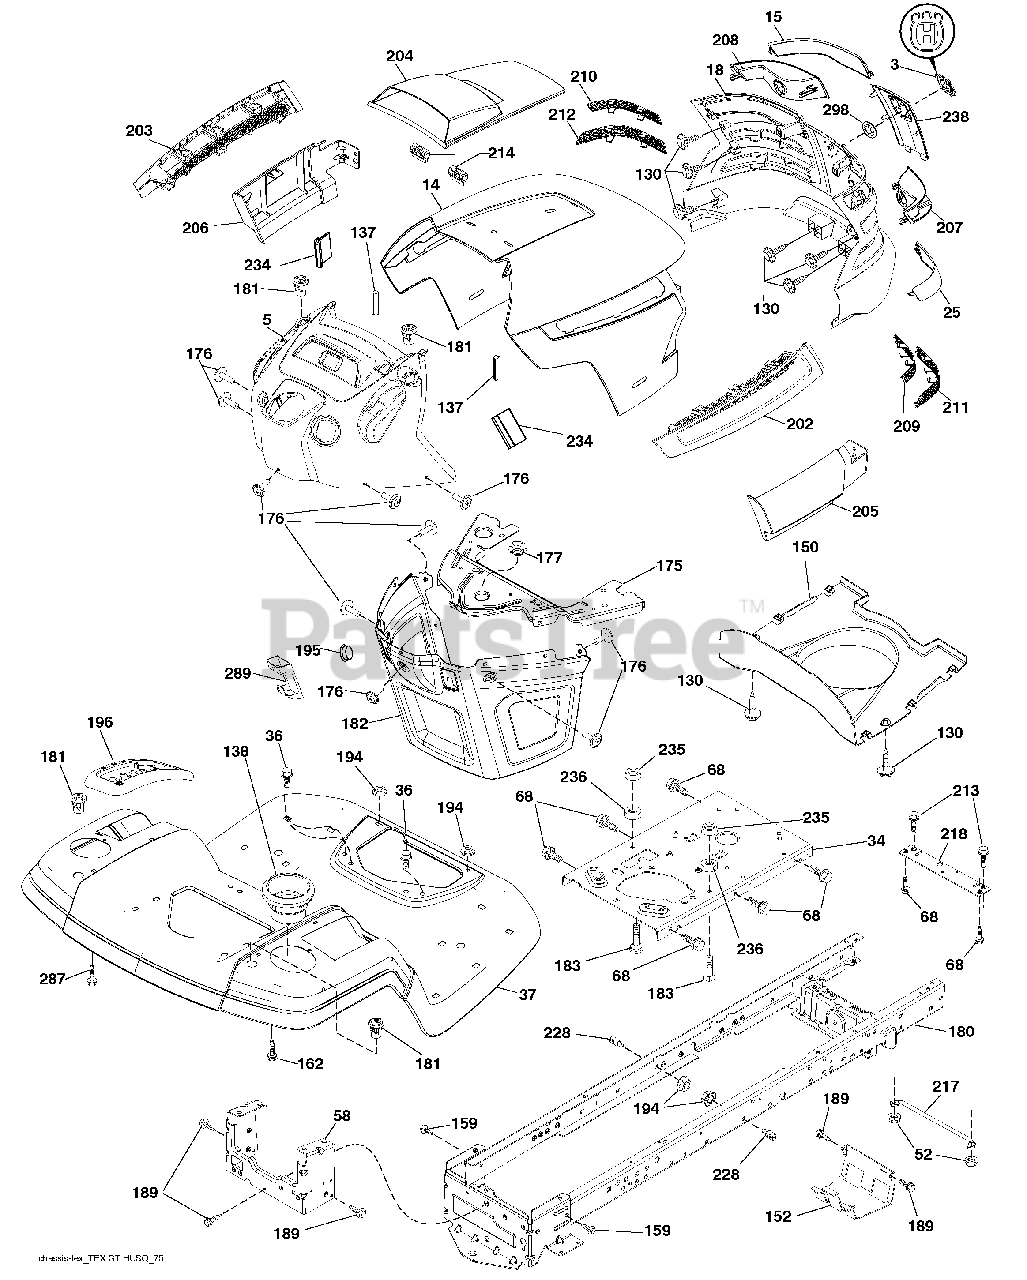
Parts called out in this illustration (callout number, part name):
3	Logo
14	Hood
34	Plate Engine
36	Screw 5/16-18 x 3/4
37	Fender
52	Nut Crown Lock 5/16
58	Drawbar Upper
68	Screw THDROL 5/16-18 x 1/2
130	Screw #10 x 0.750 BOS Thread
137	Bumper Dash
138	Cupholder
152	Shield Browning
159	Screw Hexwash Thor 3/8-16 x 3/4
175	Crossmember Plate
176	Screw 10-24 x 5/8
177	Bushing Steering
181	Bushing Mtg. Fender Crgo
182	Dash Lower
183	Bolt 5/16-18 x 1-1/4 Full Thd
189	Screw 5/16-18 x 3/4
194	Nut Lock Hex Flange 5/16-18
196	Console Asm. Deck Lift
202	Vent Side Hood RH
203	Vent Side Hood LH
204	Vent Top Hood
205	Skirt Side RH
206	Skirt Side LH
209	Insert Hex Top RH
210	Insert Hex Top LH
211	Insert Hex Bottom RH
212	Insert Hex Bottom LH
213	Bolt 5/16-18 x 3/4
214	Clip Retainer
217	Rod Pivot Hood
218	X-Piece Hood Stop
228	Stud Fastener
234	Bumper Hood
235	Spacer Fender
236	Nut Lock 5/16-18 unc
287	Screw Hex Washead 1/4-20 x 3/8
289	Plug Cruise/Phone
